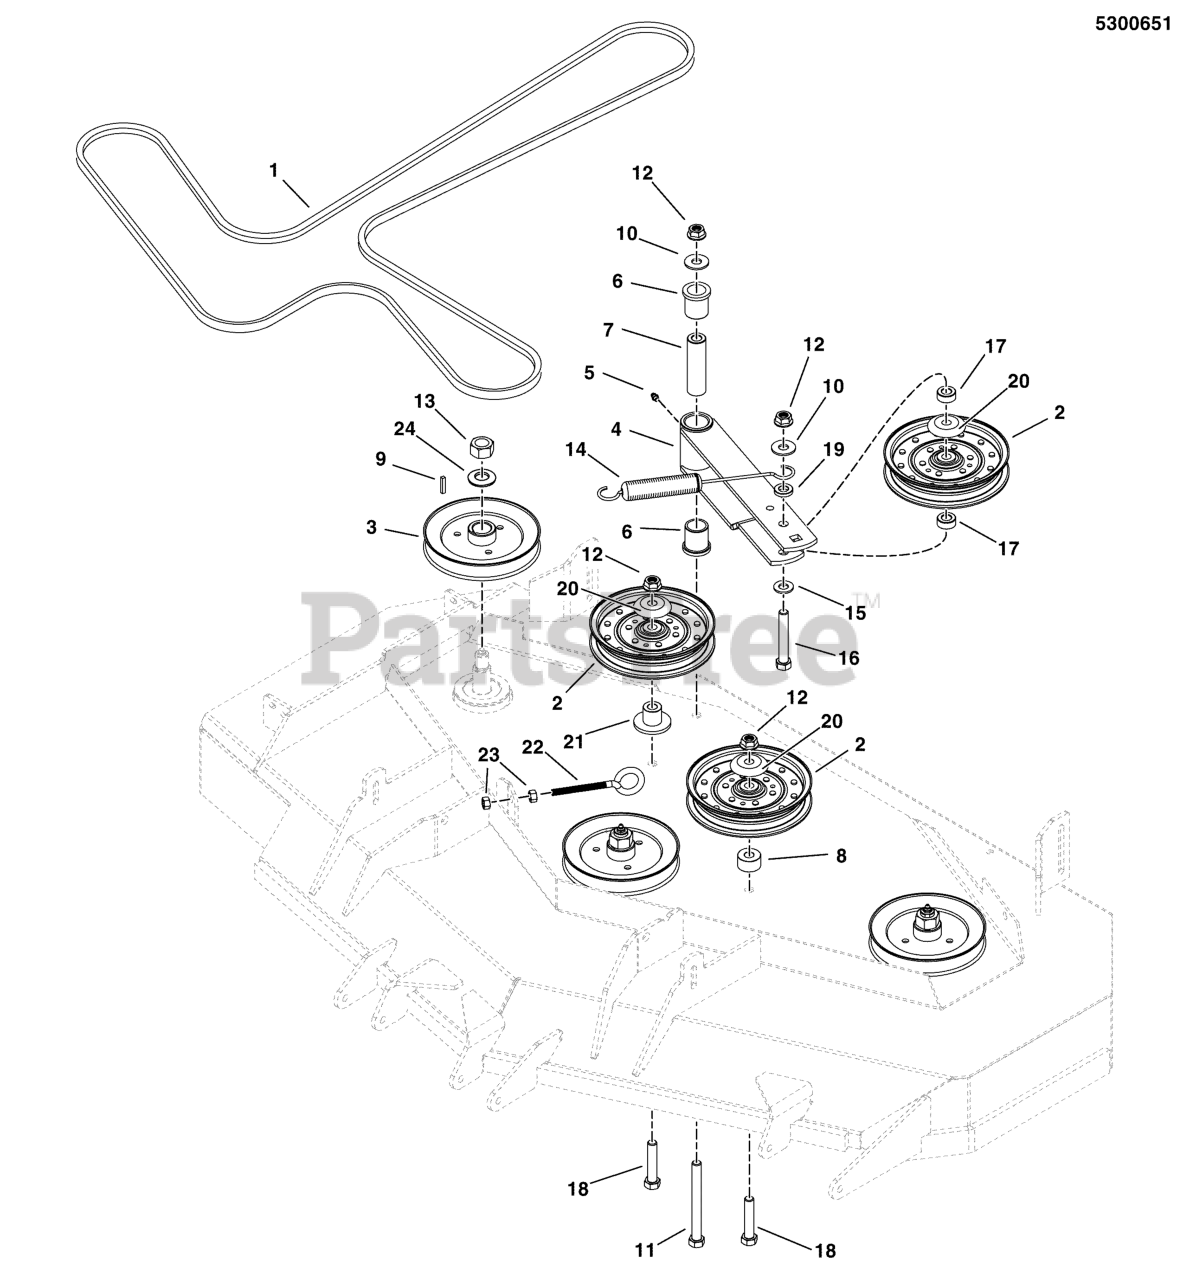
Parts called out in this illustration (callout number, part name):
1	BELT, 5V, 163.40EL, LG ARAMID, WRPD, RC
3	PULLEY, 5.926 OVER BALL
4	WELD, IDLER ARM - BLK
5	GREASE FITTING, 1/4-28 STRAIGHT
6	BUSHING, FLANGE
7	SPACER, .52 X 1.00 X 3.50
8	SPACER, .52 X 1.25 X .70, CZ
9	KEY, 1/4 SQ X 1-1/4
10	WASHER, 1/2 USS
11	BOLT-1/2-13 X 5 GD5 YZ
12	NUT, Hex Flange, Nylock, 1/2-13
13	NUT, 3/4-16 HEX
14	SPRING-EXT, 1.04 ODX10.535LGX.148WR, BLK
15	WASHER, 1/2 SAE
16	BOLT, 1/2-13 X 3-1/4, HEX HD, GD5, CZ (SV)
17	SPACER, .52 X 1.00 X .44, CZ
18	BOLT, 1/2-13 X 2-1/2" GD5 CZ
19	SPACER, .52 X 1.00 X .22, PM, CZ
20	SHIELD, PULLEY BEARING
21	IDLER MOUNT
22	EYE BOLT, 3/8-16 X 6.88, 3THRD, 1EYE
23	NUT, 3/8-16 HEX
24	WASHER, 3/4 BELLEVILLE
